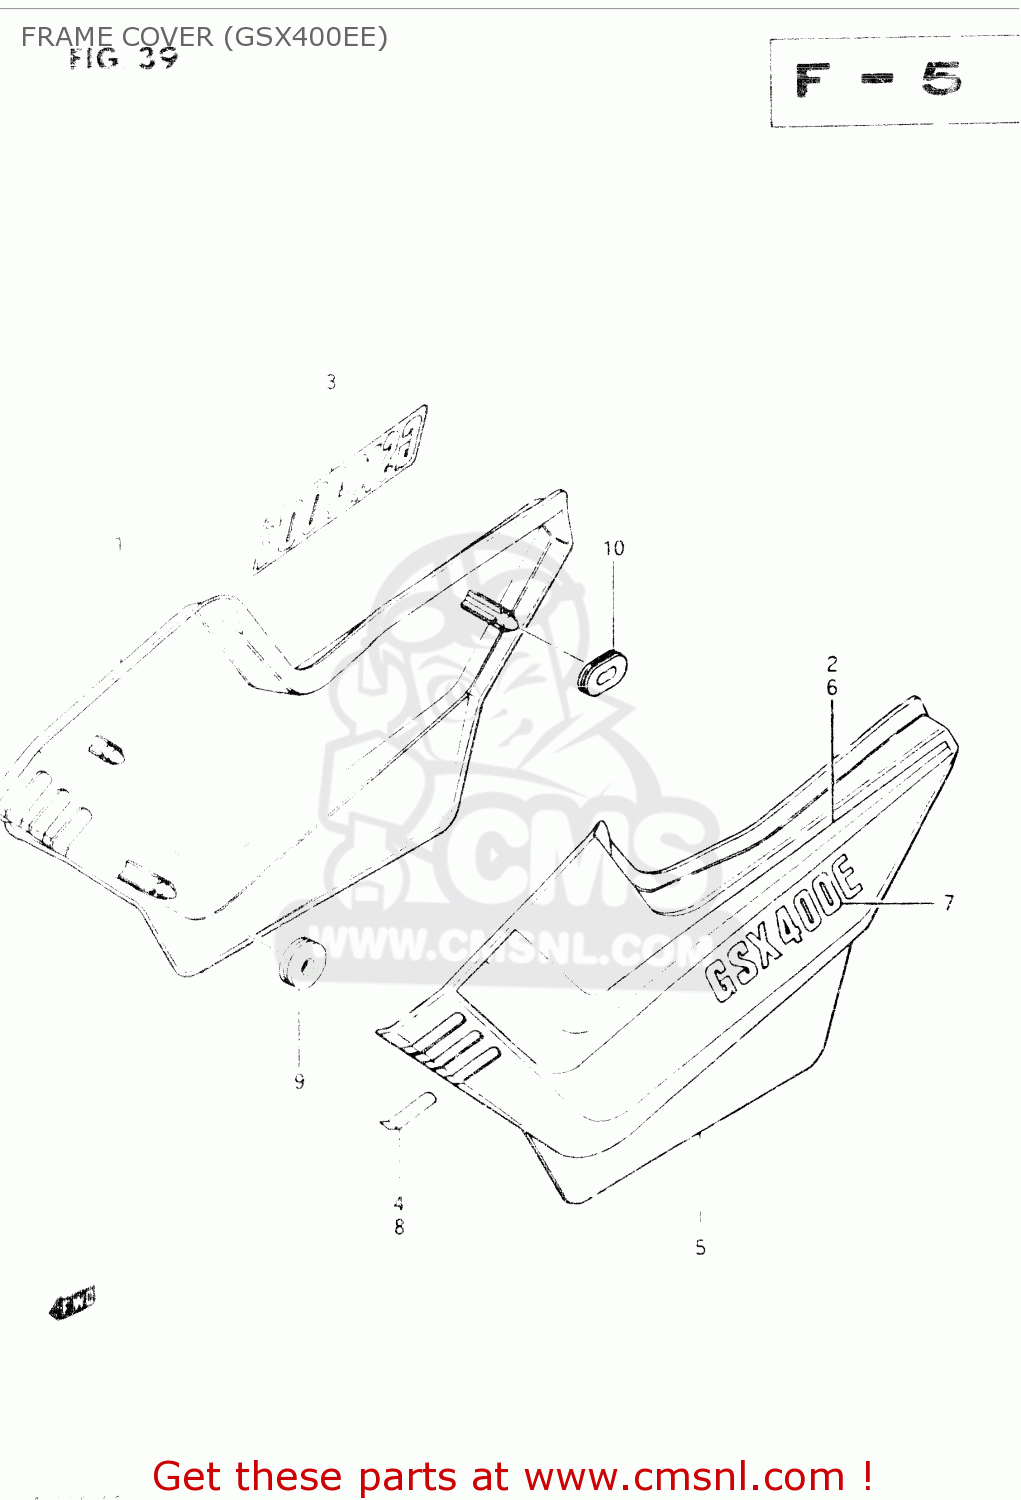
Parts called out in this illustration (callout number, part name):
1	COVER SET, FRAME RH (RED)
2	TAPE SET,FRAME
3	EMBLEM
4	LABEL,FRAME COVER DENT,R
5	COVER SET,FRAM
6	TAPE SET, FRAME COVER LH
7	EMBLEM
8	LABEL,FRAME COVER DENT
9	CUSHION
10	CUSHION
